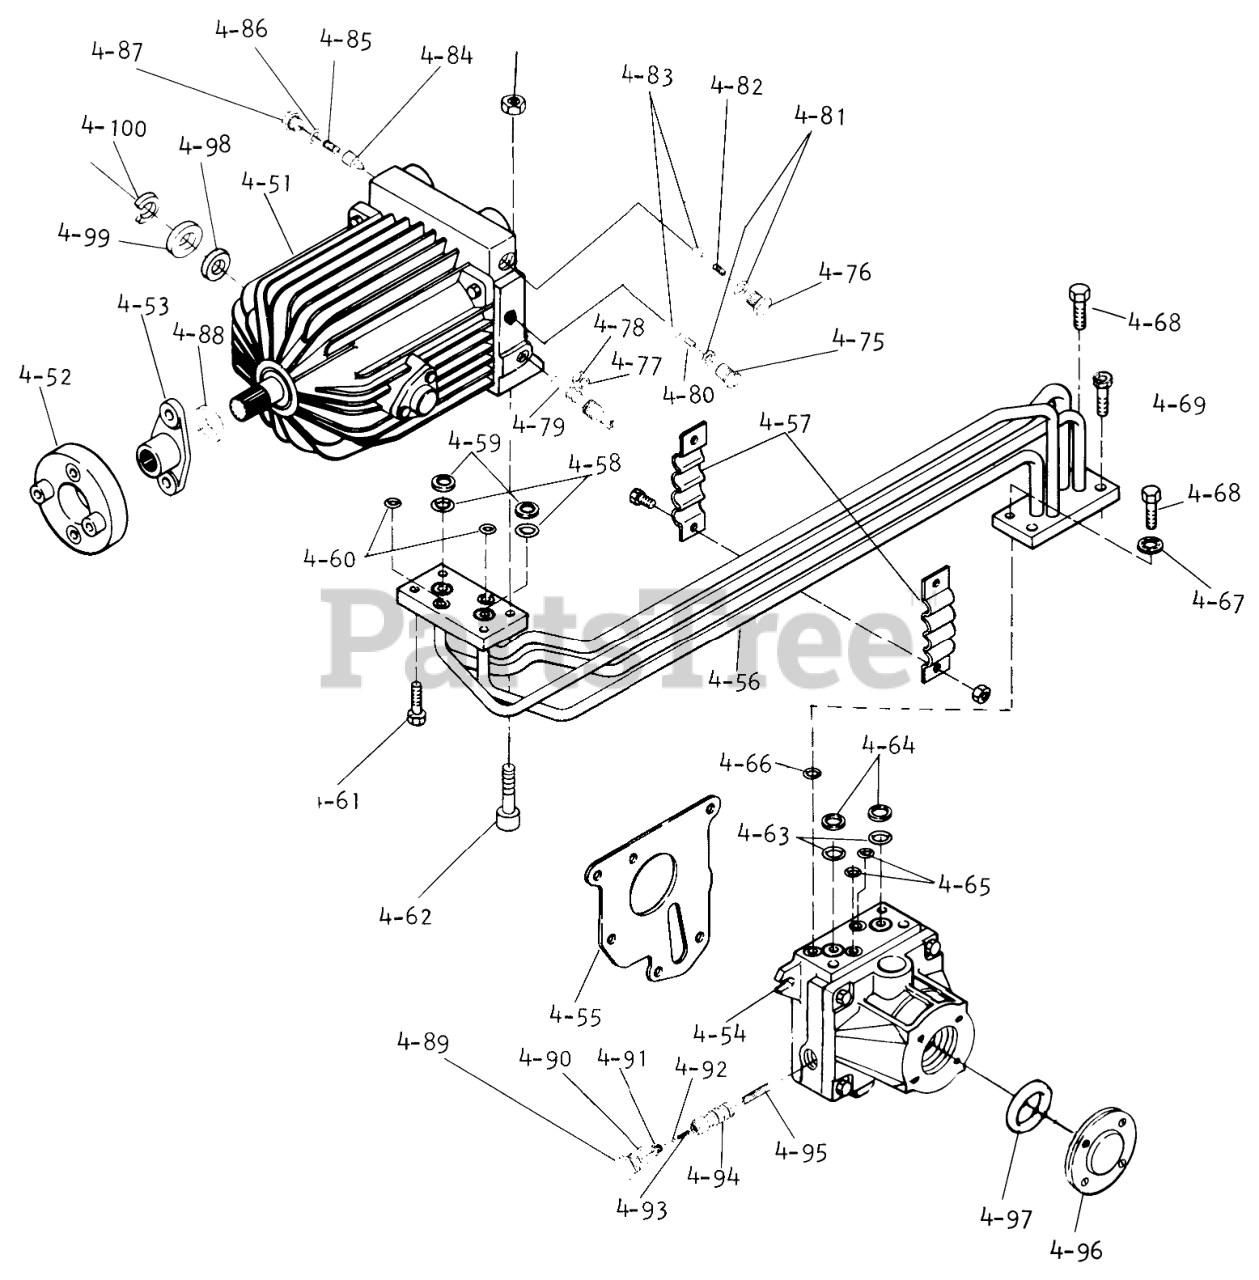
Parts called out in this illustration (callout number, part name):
4-51	Spring
4-52	Coupling
4-53	COUPLING DRIVEN R
4-54	Hydro Motor Only
4-55	GASKET
4-56	Manifold, Hydraulic
4-57	Hitch Plate
4-58	O RING
4-59	RING BACKUP
4-60	O RING
4-61	Bolt 3/8-16 x 1
4-62	Screw
4-63	O RING
4-64	RING BACKUP
4-65	O RING
4-66	O RING
4-67	SEAL-MANIFOLD BOLT
4-68	Bolt Hex 1/2-13 x 1 1/4
4-69	Bolt 3/8-16 X 1
4-75	PLUG
4-76	Plug
4-77	Back Up Ring
4-78	O-RING
4-79	VALVE
4-80	Spring
4-81	"O" Ring
4-82	Spring Chg. Rel. Valve
4-84	Cone
4-85	Spring
4-86	"O" Ring
4-88	SEAL
4-90	O-RING
4-91	Valve
4-93	SPRING
4-94	Sleeve
4-95	Spring
4-96	Plate
4-97	O-RING
4-98	SEAL
4-99	WASHER-LAMBERT
4-100	RING-LAMBERT
